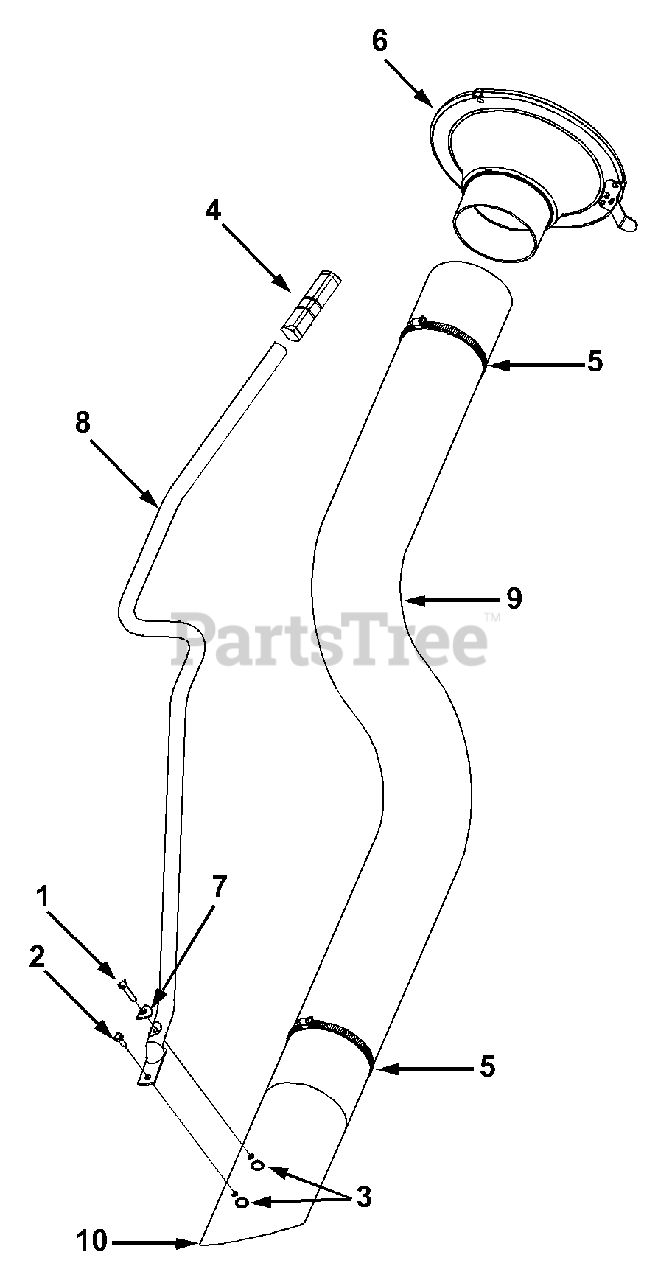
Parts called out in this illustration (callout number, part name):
1	Hex Bolt 1/4-20 x 1.25" Lg.
2	Hex Bolt 1/4-20 x .62" Lg.
3	Hex L-Nut 1/4-20 Thd.
5	Adj. Hose Clamp 5" Dia.
6	Hose Adapter
7	Saddle Washer .32" I.D.
9	Hose - 5" Dia.
10	Nozzle Tube
